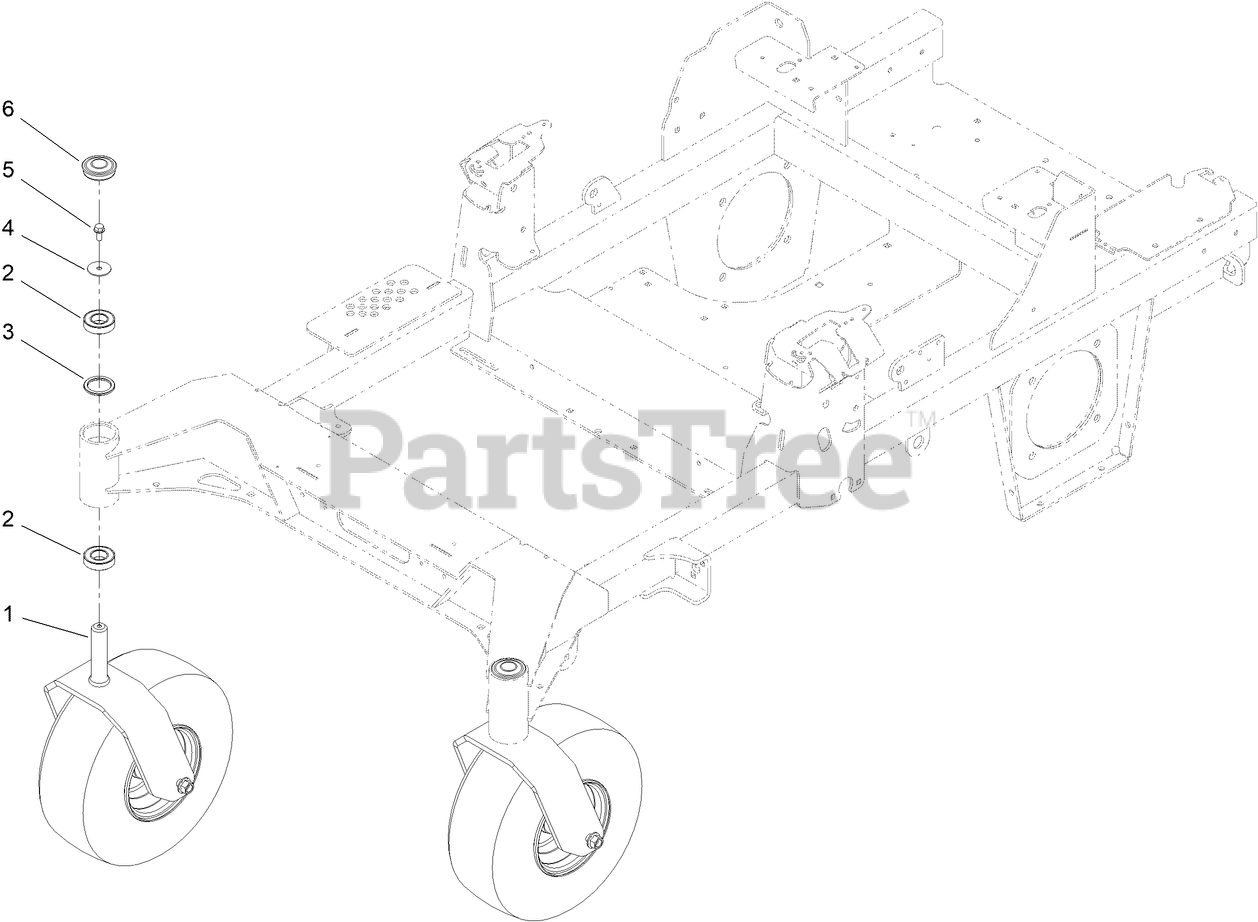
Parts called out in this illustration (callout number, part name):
1	ASM-FRONT CASTER W/FORK
2	BEARING-BALL
3	SPACER-BEARING
4	WASHER-FLAT
5	SCREW-HHF
6	CAP,GREASE
